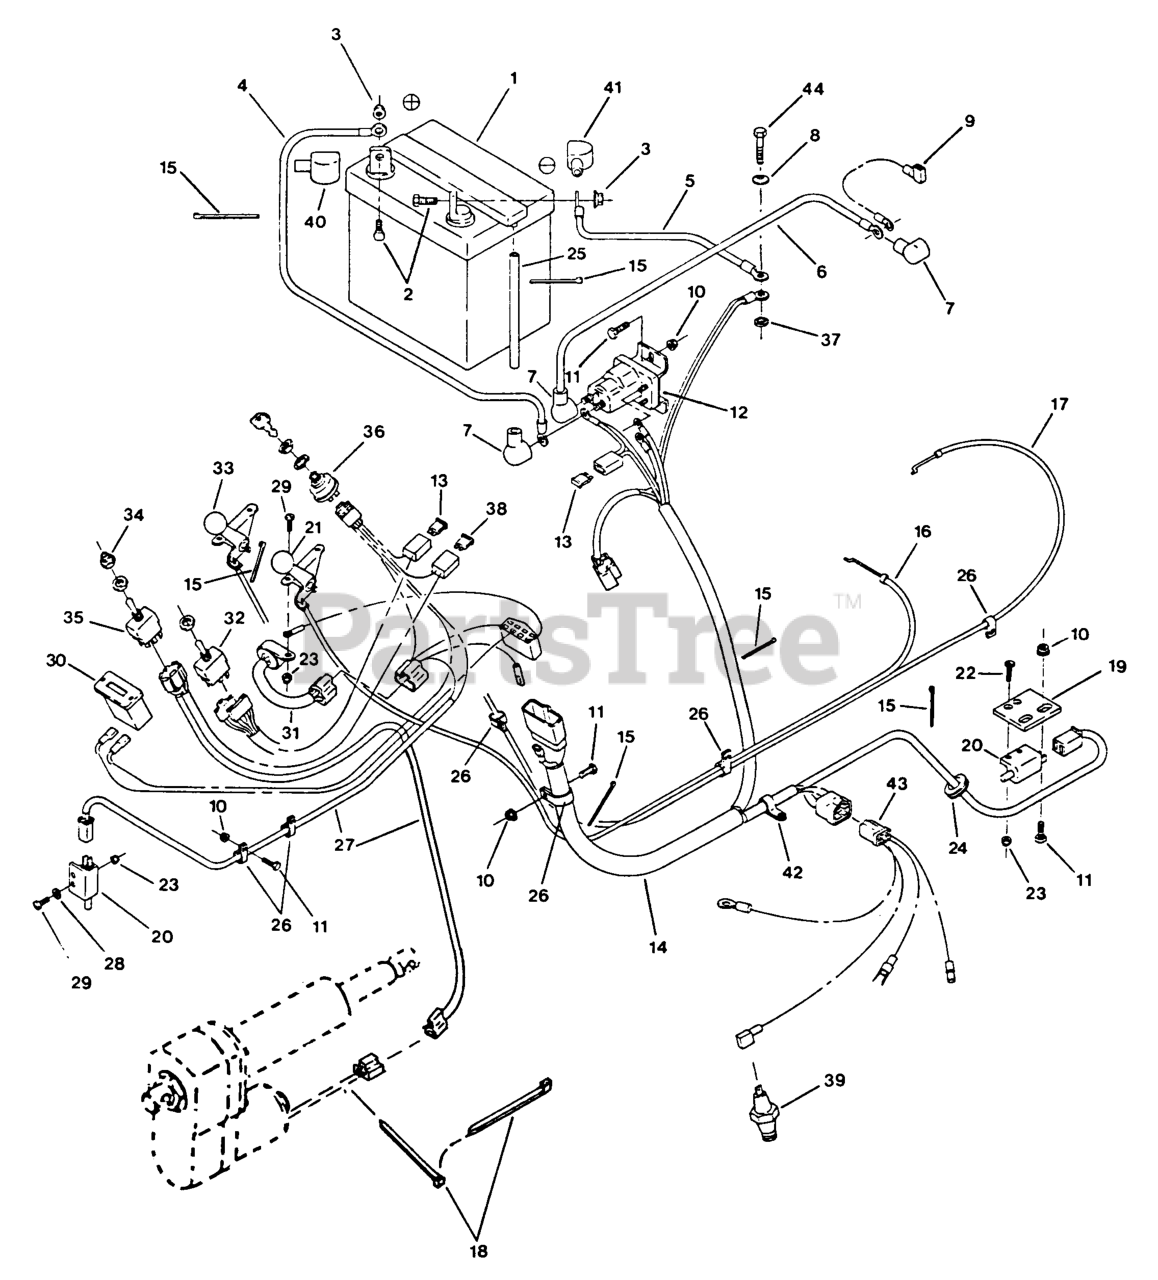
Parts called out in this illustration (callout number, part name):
1	Battery, 12v Manifold
5	WIRE-GROUND
7	INSULATOR-SOLENOID
8	WASHER-SPRING
13	FUSE-BLADE TYPE, 20 AMP
15	TIE-CABLE
18	TIE-PLASTIC
19	BRACKET,SAFETY SWITCH
20	SWITCH-OPEN, NORMALLY
21	KNOB-BALL
24	GROMMET
26	CLIP-LOOM
30	METER-HOUR
32	SWITCH,W/TERM CLIPPD
33	KNOB-BALL, BLACK
34	BOOT-SWITCH, TOGGLE
35	SWITCH-TOGGLE, DPDT
36	SWITCH,IGNITION
38	FUSE-BLADE TYPE, 30 AMP
39	SWITCH-OIL PRESSURE
41	INSULATOR, BATTERY -
42	CLIP-LOOM
43	WIRHRNS,ENG ADAPTER
